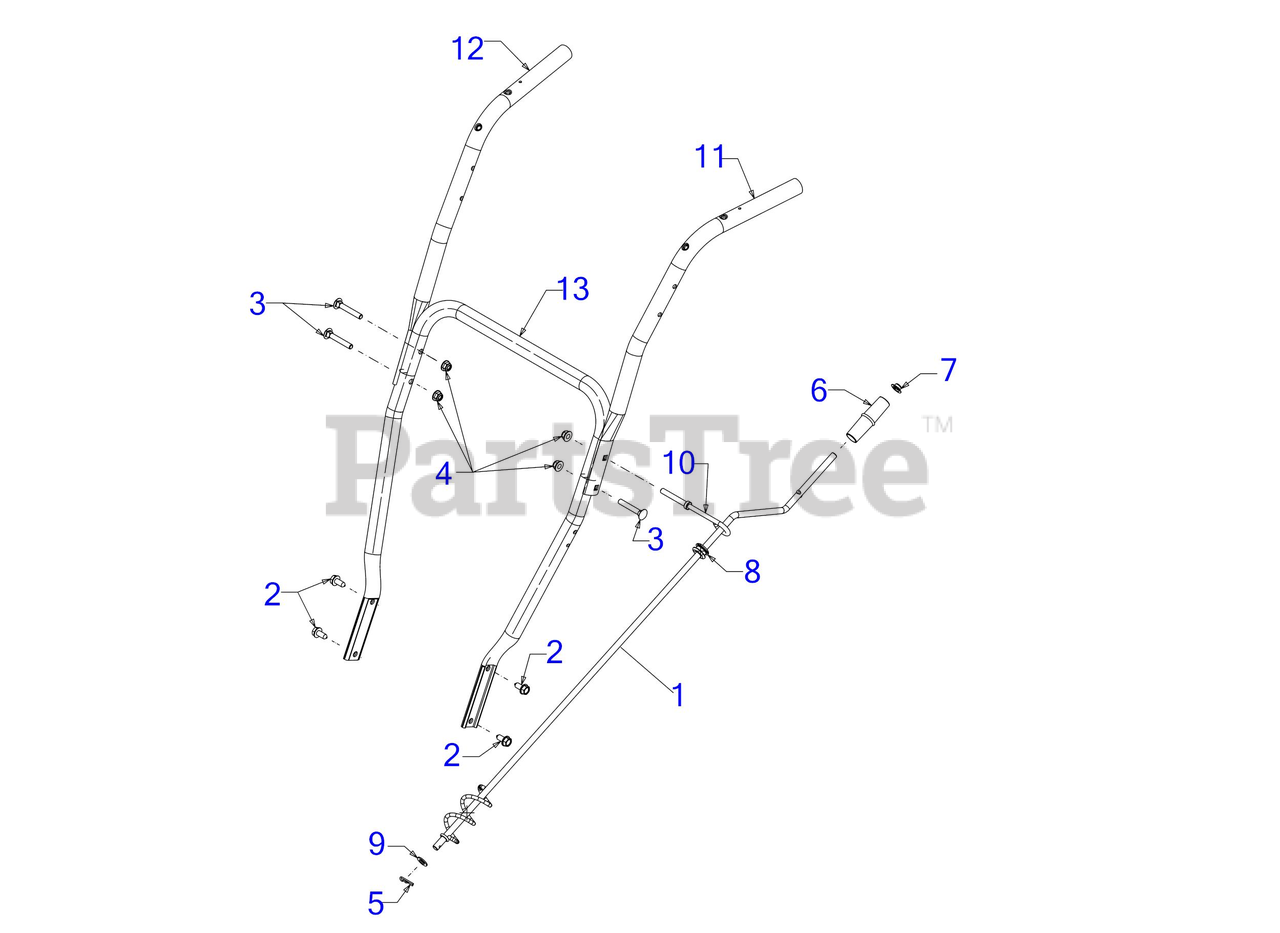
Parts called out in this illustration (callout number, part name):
1	CHUTE CRANK ASSEMBLY
2	SCREW 5/16-18 x .750
3	CARRIAGE BOLT 5/16-18 x 2.00 GR5
4	FLANGE LOCK NUT 5/16-18
5	COTTER PIN .072 DIA
6	CRANK KNOB
7	PUSH NUT
8	GROMMET
9	FLAT WASHER
10	CHUTE CRANK EYEBOLT
